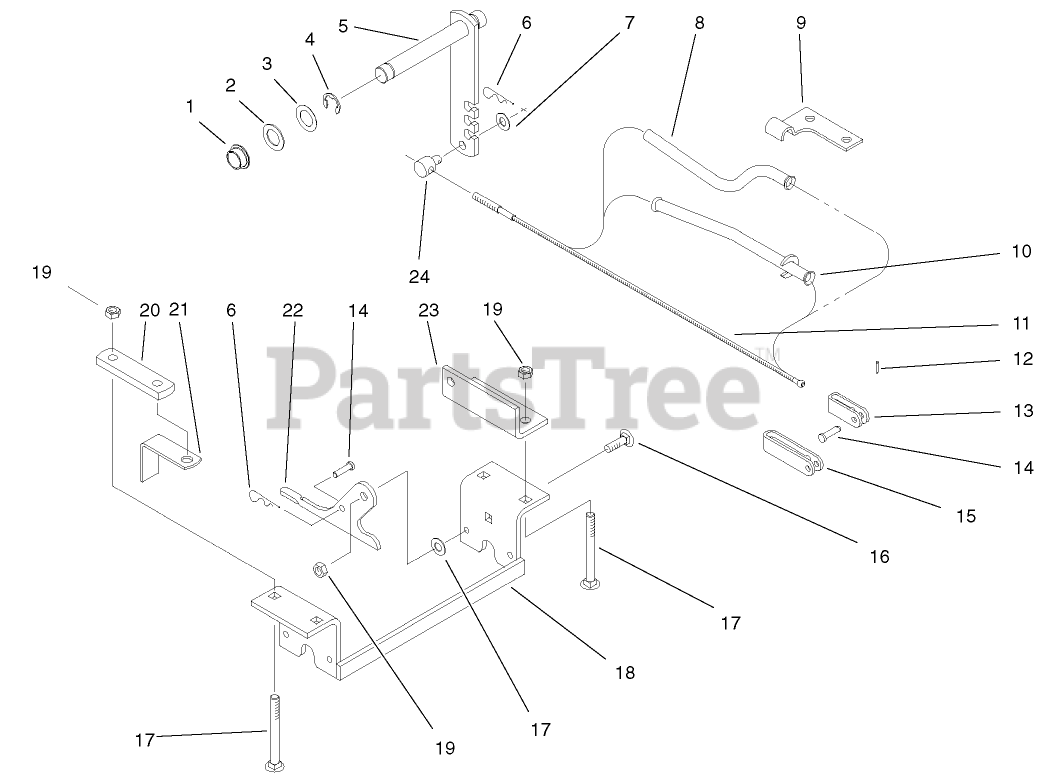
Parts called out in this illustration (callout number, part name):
1	BUSHING-BRONZE
2	WASHER
3	WASHER-SHIM
4	E-RING
5	Lever ASM
6	PIN-HAIR
7	WASHER-FLAT
8	Tube-Conduit, 8 Speed
9	Clamp-Conduit
10	Conduit Tube ASM
11	CABLE
12	PIN-COTTER
13	CLEVIS-SHORT
14	PIN-CLEVIS
15	CLEVIS-LONG
16	BOLT-CARR
17	SCREW-CARR
18	BRACKET-AXLE
19	NUT-HEX
20	BRACKET-REAR LINK MOUNTING
21	SPACER-BRACKET
22	PLATE-LATCHING
23	Link-Bracket
24	TRUNNION-CLUTCH ROD
